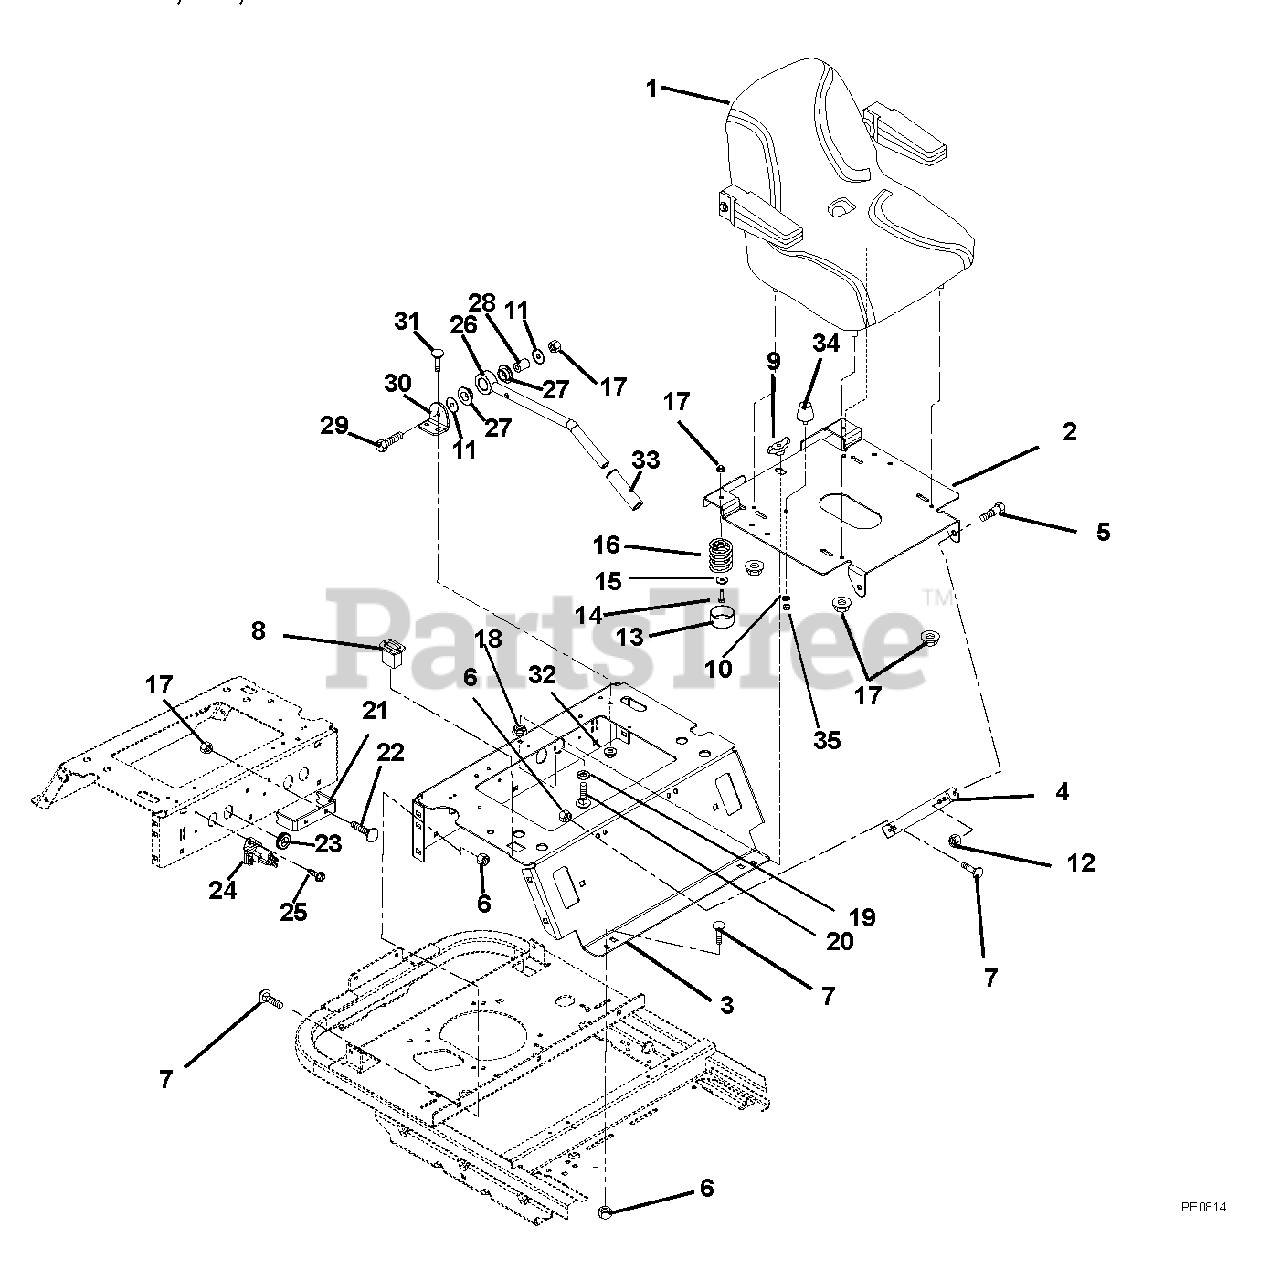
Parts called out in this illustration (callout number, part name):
1	Seat w/Armrests
2	Seat Plate
3	Seat Support
4	Bracket, Seat Plate
5	Bolt, Shoulder .375-16 x .135
6	Nut .38-16 Flange Nyloc
7	Bolt, Round Head Square Neck .38-16 x 1.00 Grade 5
8	Hour Meter, LCD
9	Knob, Wing .312-18
10	Washer-Locking .31 x .078 Regular
11	Washer-Flat-Steel .347 x 1.254 x .048
12	Nut-Locking-Top-Flange .38-16
14	Bolt-Hex .31-18 x 1.00 Grade 5
15	Washer-Flat-Steel .328 x 1.0 x .094
16	Spring, Seat
17	Nut .312-18 Flange Nyloc
18	Nut-Spin Lock-Flange .312-18
19	Washer-Flat-Steel .505 x 1.00 x .062
20	Bolt-Round Head Square Neck .31-18 x 2.75 Grade 5
21	Brake Rod Support
22	Bolt, Round Head Square Neck .31-18 x 1.00
24	Solenoid
25	Screw, Tapping .250-20 x .37
26	Weldment, Park Brake
27	Bushing, Flange .762 x 1.48 x .44
28	Spacer .328 x .76 x 1.01
29	Bolt, Hex .31-18 x 1.75 Grade 5
30	Bracket, Brake Handle Pivot
31	Bolt, Round Head Square Neck .25-20 x .75 Grade 5
32	Nut, Locking Top Flange .25-20
33	Grip
34	Bumper, Rubber
35	Nut, Spinlock Flange Nut, .312-24
